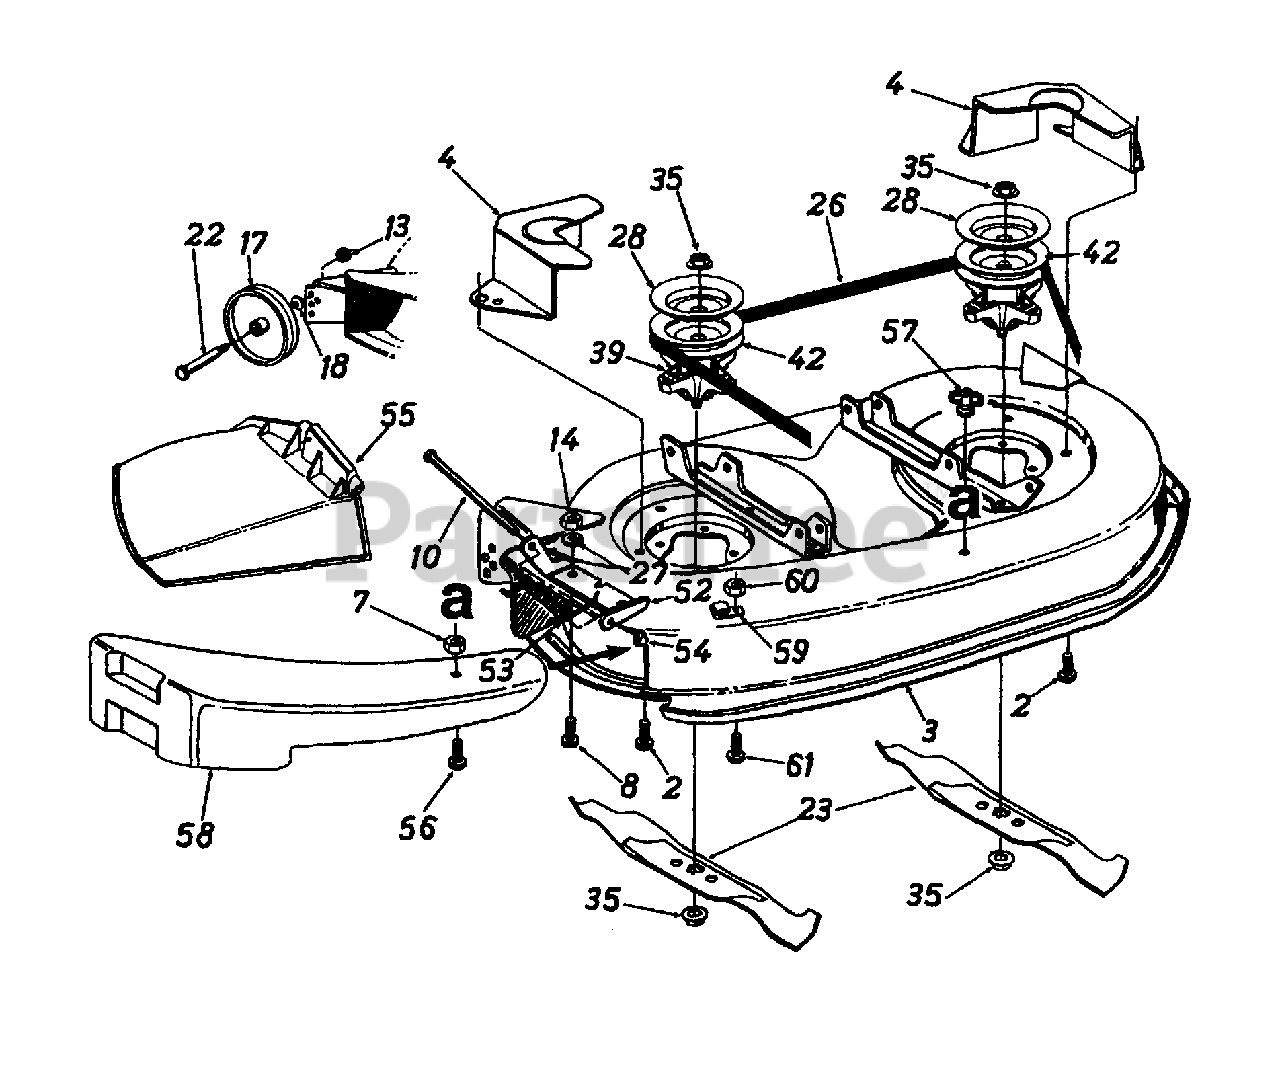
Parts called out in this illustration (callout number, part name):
2	Hex Wash. Hd. TT-Tap Scr. 5/16-18 x .75" Lg.
7	Hex L-Nut 1/4-20 Thd.
8	Hex Bolt 1/4-20 x .62"
10	Hinge Pin
13	Hex Top L-Nut 3/8-16 Thd.
14	Hex Nut 1/4-20 Thd. (Gr. 5)
17	Deck Wheel - 5"
18	Bell-Wash. .40" I.D. x.88" O.D.
22	Shld. Bolt .498" Dia. x 1.53"
23	3 in 1 Blade
26	V-Belt
27	Bell-Wash. 1/4" I.D.
28	Brake Disc
35	Hex Flange Nut 5/8-18 Thd.
39	Blade Spindle Ass'y. Comp.
42	5.75" Dia. Pulleys
52	Hinge Mtg. Brkt.
53	Torsion Spring
55	Chute Ass'y. Comp.
56	Hex Bolt 1/4-20 x 1" Lg.
57	Wing Nut 1/4-20 Thd
58	Mulching Plugs
59	Retainer Hook Brkt.
60	Hex Sems Nut 1/4-20 Thd.
61	Hex Bolt 1/4-20 x .62" Lg.
